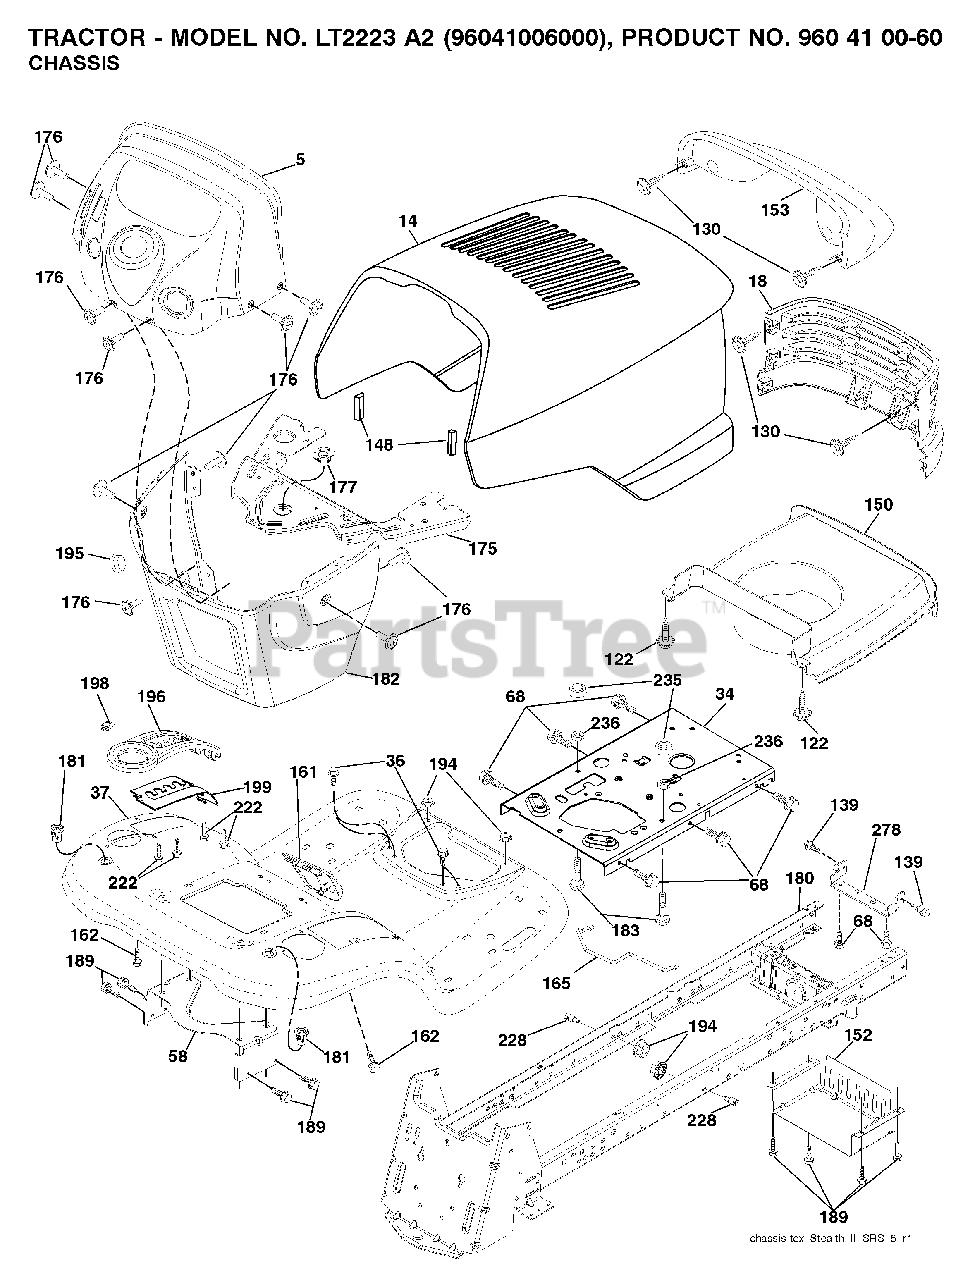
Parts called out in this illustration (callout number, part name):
34	PLATE.ENGINE.WELDED.CHASSIS
36	SCREW 5/16"
58	BRKT.SUPPORT.FNDR/TANK
122	SCREW.WSHD.HEX10-32X5/8
130	SCREW
139	BOLT, SHOULDER 5/16-18
148	EXTRUSION BUMPER
150	DUCT HOOD
152	SHIELD BROWNING
161	CONSOLE.FUEL.WINDOW.STGT.BLACK
162	SCREW.HI-LO.CONSOLE
165	SUPPORT.TANK.REAR.W/TE
175	CROSSMEMBER.
176	SCREW.#10-24X5/8.RN.QU
177	BUSHING,STEERING
180	CHASSIS.GT.SLOPED.DRAWBAR.
181	FEND/FTRST.PCH.CPH.NFW
182	DASH.LOWER.
183	BOLT.5/16-18X1-1/4 FULL.THREAD
189	SCREW
194	NUT LOCK HEX FLANGE 5/16-18
195	PLUG.HOLE.DASH.LOWER.12V.BLK
198	INDICATOR DECK LIFT
199	PLATE DECK LIFT
222	SCREW.1/4-20X5/8
228	STUD.FASTNER.W/ANTI-ROTATE
235	SPACER FENDER
236	NUT.CENTERLOCK.5/16-
278	BRKT.HOOD/MUFF.STEALTH
